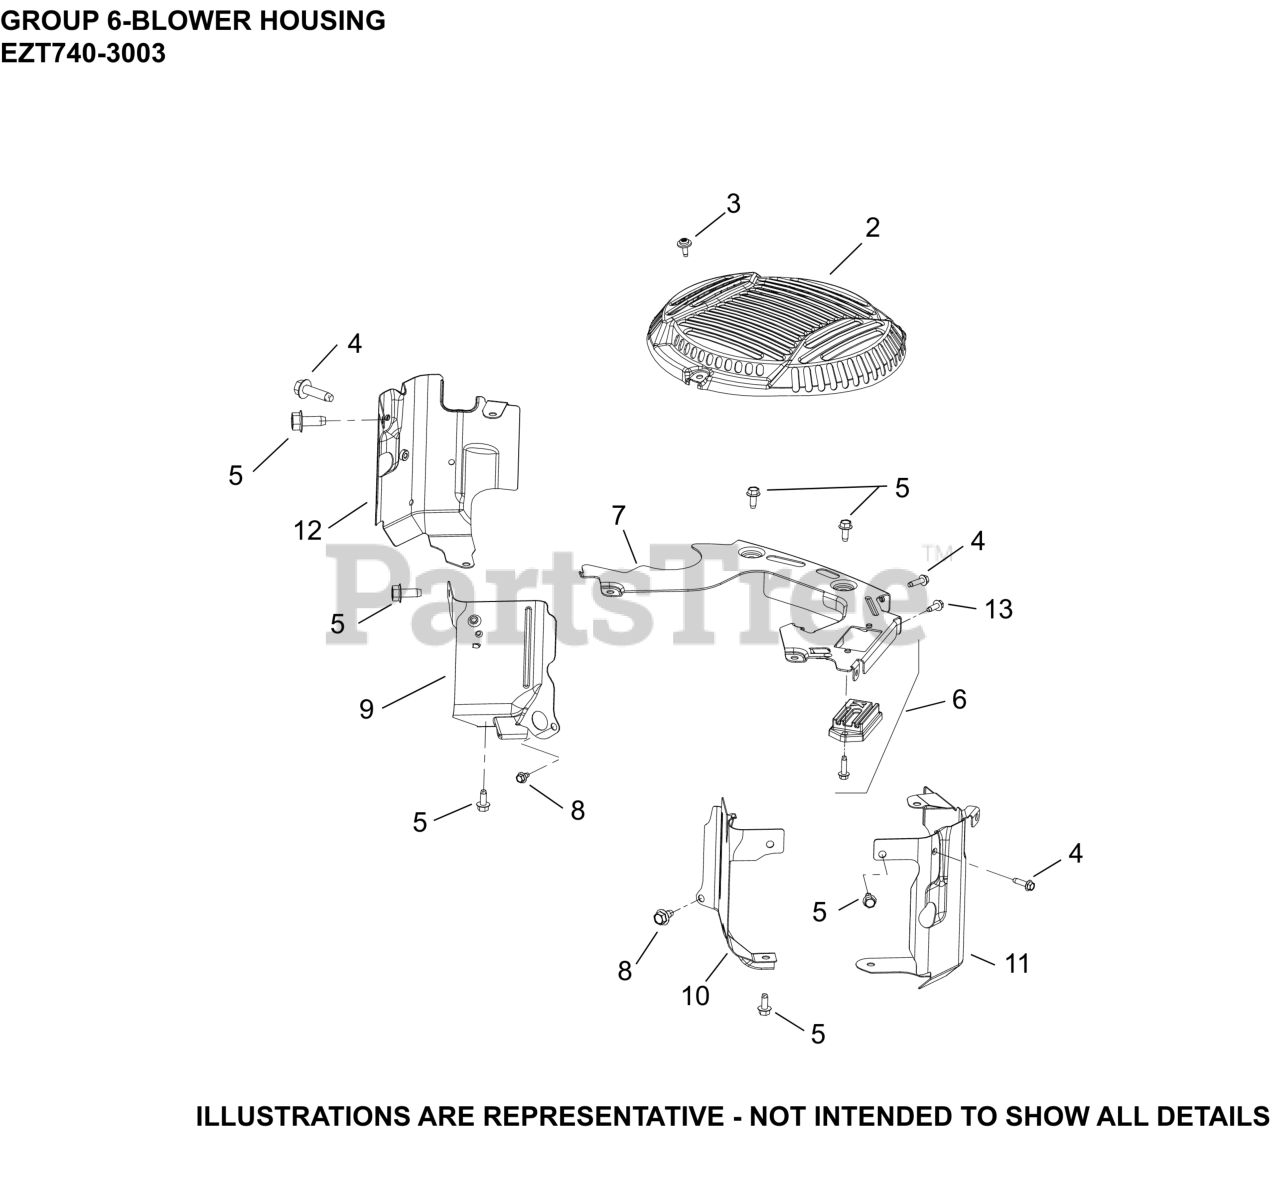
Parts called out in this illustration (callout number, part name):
2	GUARD, GRASS SCREEN (METAL)
3	SCREW, SEMS
4	SCREW, THD FRM-USE 25 086 473-S
5	SCREW, THREAD FORMING
6	PLATE ASSEMBLY, BACKING (15A)
7	PLATE, BACKING
8	SCREW, THREAD FORMING
9	BAFFLE, VALLEY #1
10	BAFFLE, VALLEY #2
11	BAFFLE, LEFT BARREL
12	BAFFLE, RIGHT BARREL
13	SCREW, THREAD FORMING
NI	KIT, BLOWER HOUSING
